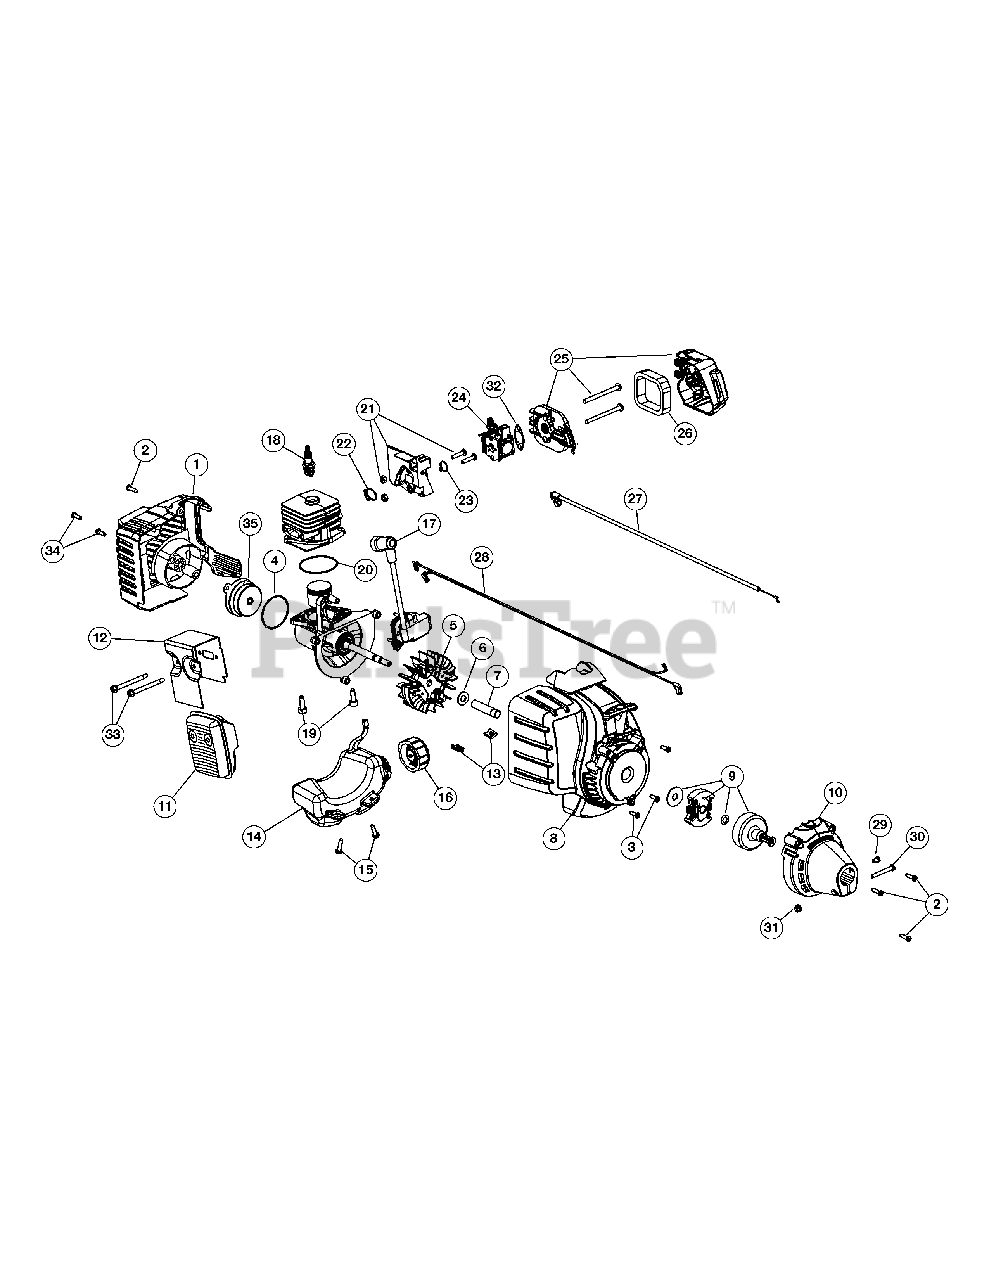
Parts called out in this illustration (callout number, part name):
1	Rear Cover Assembly (Incl. 2 & 34)
2	Cover Screw
3	Housing Screw
4	O-Ring
5	Flywheel Assembly
6	Washer
7	Spacer
8	Starter Housing (Incl. 3 & 13)
9	Clutch Assembly
10	Clutch Cover (Incl. 2)
11	Muffler Assembly (Incl. 12 & 33)
12	Muffler Gasket
13	U-shaped Nut
14	Fuel Tank Assembly (Incl. 15 & 16)
15	Tank Screw
16	Fuel Cap
17	Module Assembly
18	Spark Plug
19	Crankcase Bolt
20	Crankcase O-Ring
21	Insulator Assembly (Incl. 22 & 23)
22	Insulator O-Ring
23	Carburetor O-Ring
24	Carburetor
25	Aircleaner Cover Assembly (Incl. 26)
26	Aircleaner Filter
27	Throttle Cable
28	Lead Wires
29	Anti-rotation Screw
30	Clamp Screw
31	Clamp Nut
32	Air Cleaner Gasket
33	Muffler Screw
34	Rear Housing Screw
35	Electric Starter Cover Assembly
